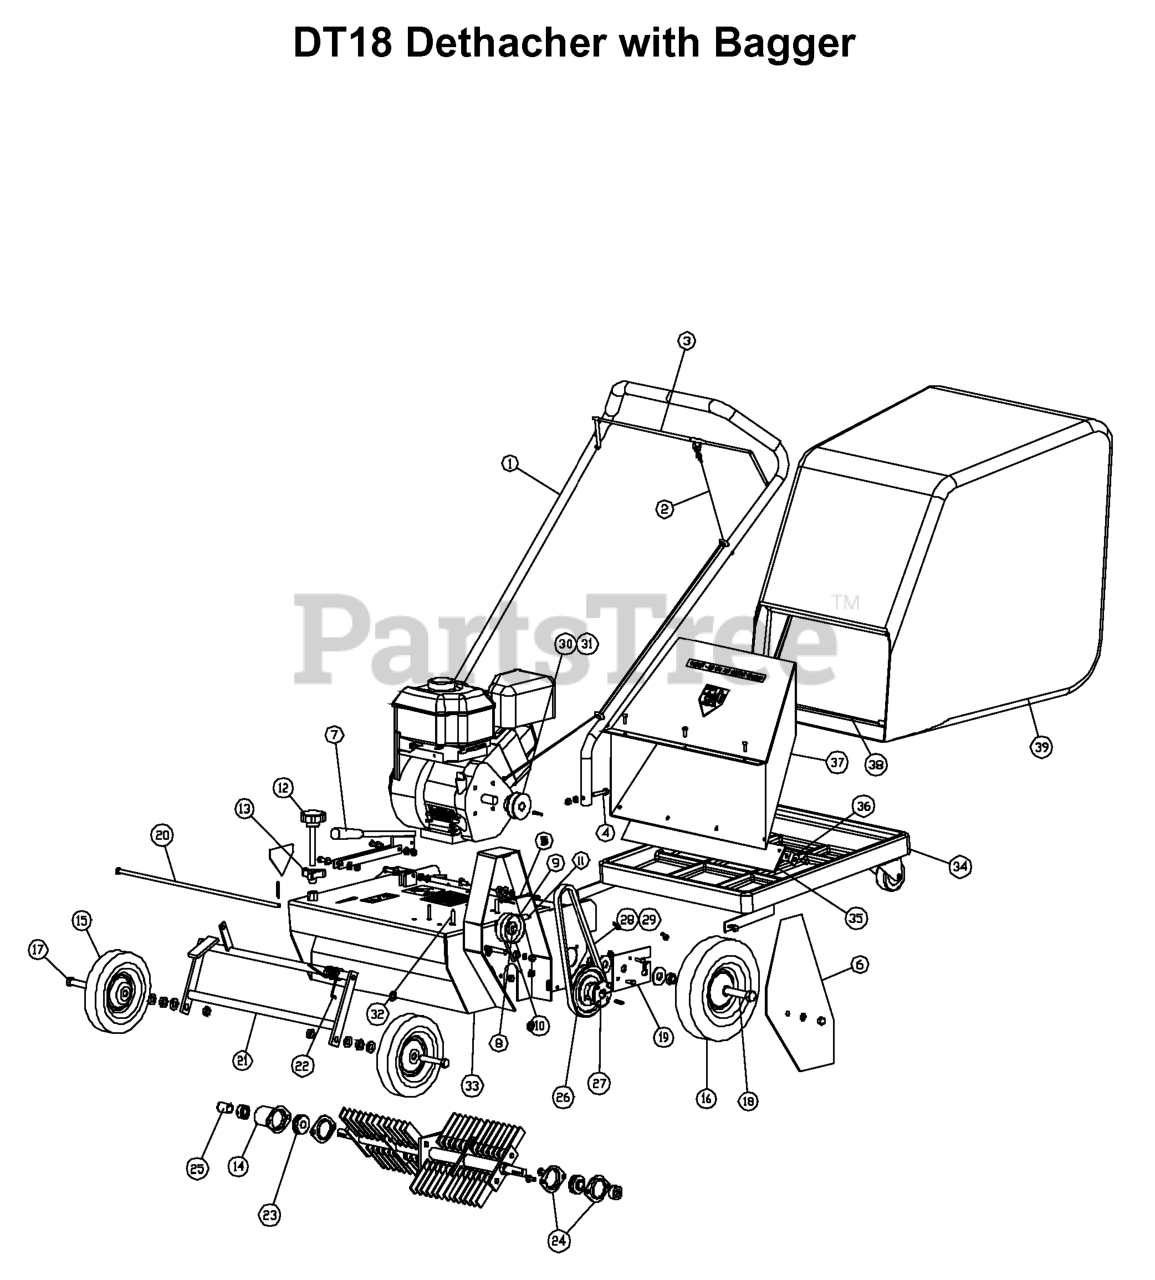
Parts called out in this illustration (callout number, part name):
1	KIT, HANDLE ASSY
2	CLUTCH CABLE
4	BOLT KIT
5	BELT KEEPER KIT
6	BELT GUARD KIT ORN
7	DEPTH LEVER ASSY
8	IDLER ASSY KIT
9	PULLEY
10	MTG ARM, IDLER PULLEY
11	SPRING
12	DEPTH ADJUSTMENT KNOB
13	3-PRONGED LOCK DEPTH
14	ROTOR GUARD
15	WHEEL
16	REAR WHEEL
17	BOLT KIT
18	BOLT KIT
19	WHEEL PLATE KIT
20	LIFT ARM ROD KIT
21	LIFT ARM ASSY OR
22	TORSION SPRING
23	BEARING
24	STAMPING KIT
25	ROTOR CAP
26	V-PULLEY
27	BUSHING KIT
28	V-BELT
29	V-BELT
30	V-PULLEY
31	V-PULLEY
32	ENGINE BOLT KIT
34	KIT BAGGER PLATFORM
35	NEOPRENE DEFLECTOR
37	CHUTE WELDMENT KIT
38	BAGGER FRAME
39	CATCHER BAG
40	Bagger conversion kit
